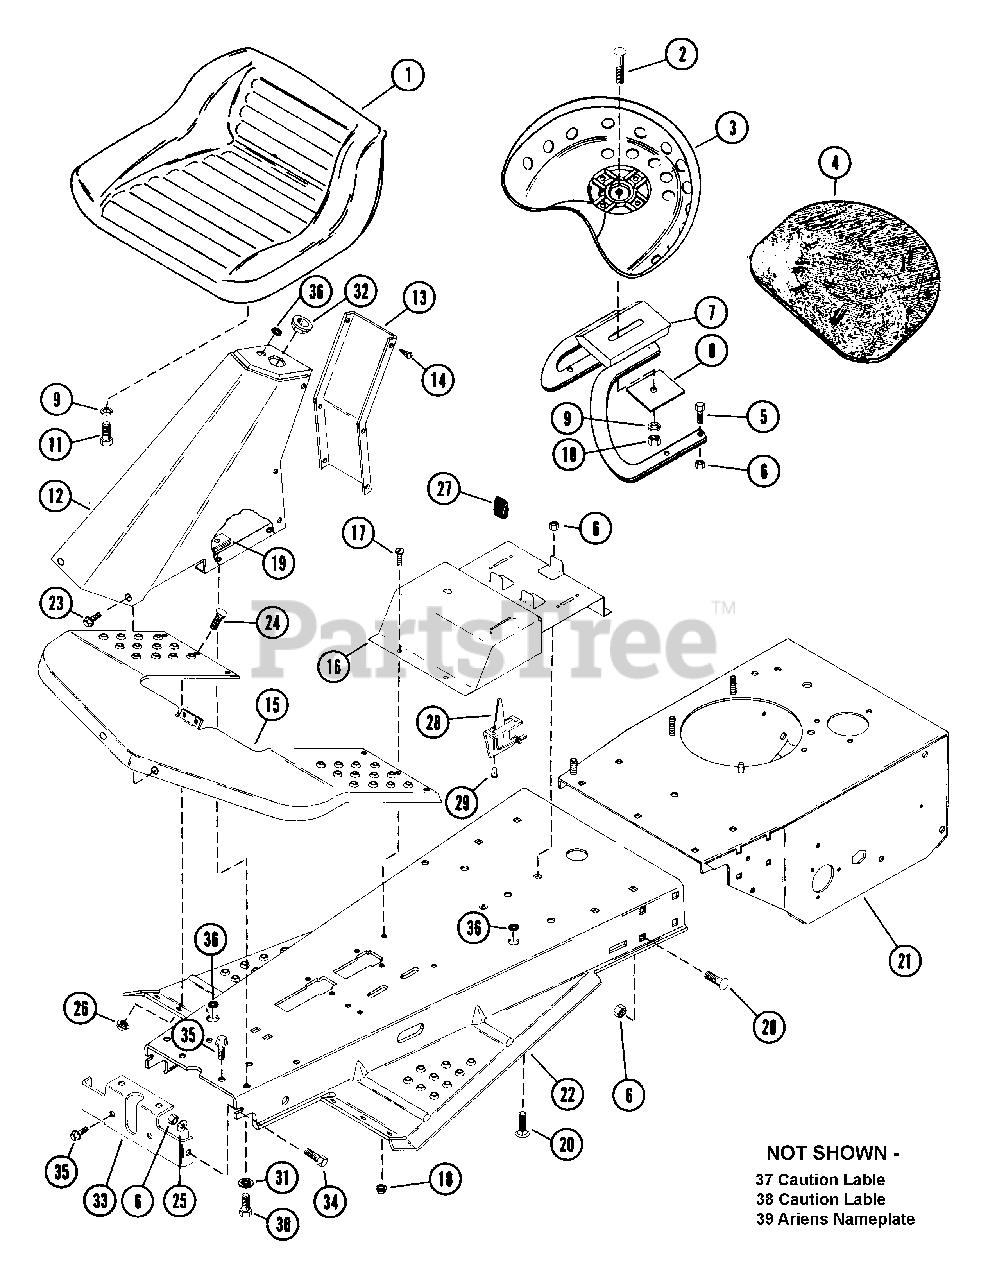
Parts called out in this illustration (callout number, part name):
1	SEAT
2	BLT-RDHDSQNK .50-13X1.25 PL
3	SEAT
4	SEAT COVER
5	BLT-HEX .31-18X1.50 PL GR2
6	NUT-LK .312-18 GR A PL
7	SEAT BRACKET
8	SEAT SUPPORT WASHER
9	WSHR-LK .500X.151 HVY PL
10	NUT .50-13 PL
11	BLT-HEX .50-13X1.25 PL GR2
12	STEERING COLUMN
13	STEERING COLUMN COVER
14	SCR-TAP 10-12X.50 CRPH PL A
15	FRONT FENDER
16	DASH PANEL
17	SCR-MCH .25-20X.63 CRPH PL
18	NUT-LK-FLG .250-20 PL
19	NUT-SPEED U-TYPE .312-18
20	BLT-RDHDSQSHNK .31-18X.50 YZ
21	REAR FRAME
22	FRONT FRAME
23	SCR-TAP 10-24X.375 CRPH 1A
24	SCR-SLTR-SERNK .25-20X.62 PL
25	WSHR-FL-STL .38X.875X.083 PL
26	NUT-LK-FLG .250-20 PL
28	THROTTLE CONTROL
29	RVT-POP.125 X .294 DOME
30	BLT-HEX .31-18X.75 PL GR2
31	WSHR-LK-INT .313X.030 PL
32	FLANGE BUSHING
33	FRONT FRAME SUPPORT
34	BLT-HEX .31-18X.50 PL GR2
35	BLT-SERHFWH .31-18X.75 PL
36	GROMMET, .31 ID
37	SAFETY LABEL
38	CAUTION LABEL
39	ARIENS NAME PLATE
